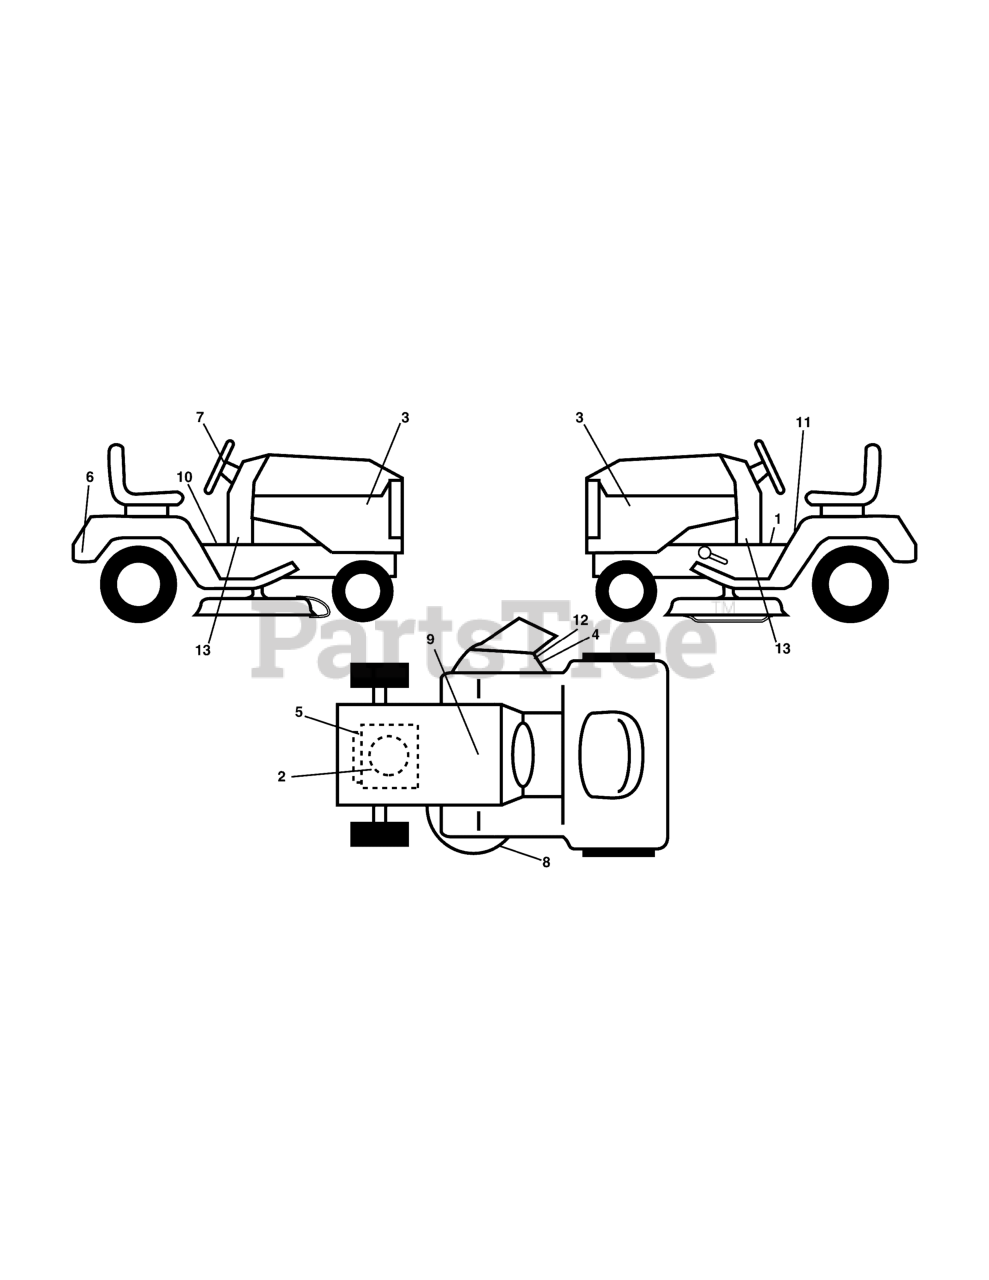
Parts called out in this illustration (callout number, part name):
1	Decal, Saddle Brake Parking
2	Decal, Warning Eng. Sym.
3	Decal, Hood LH/RH
4	Decal, Cutfinger Warning
5	Decal, Engine HP
6	Decal, Fender
7	Decal, Steering Wheel
8	Decal, B-Belt Schematic
9	Decal, Battery Dnge/Poi
10	Decal, Brake/Clutch Symbol
11	Decal, Warning CE
12	Decal, Cutfinger
13	Decal, LWDSH
